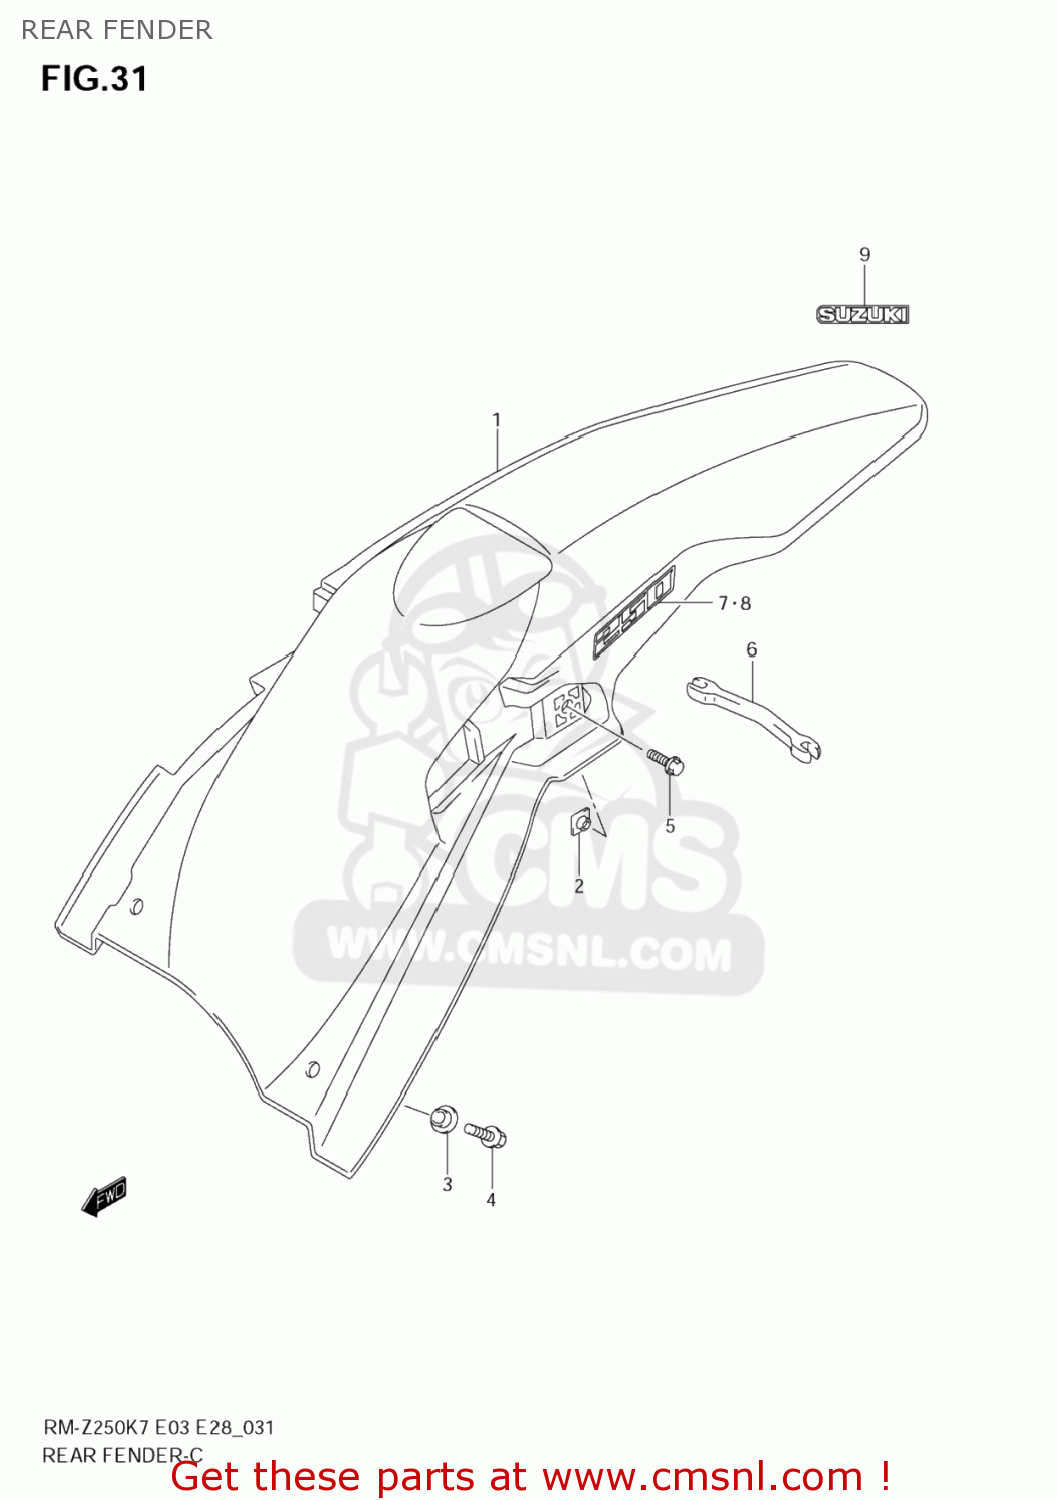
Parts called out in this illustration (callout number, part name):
1	FENDER,RR
2	NUT
3	WASHER
4	BOLT,6X20
5	BOLT(6X16)
6	OPEN SPANNER(6.4X6.8)
7	TAPE,RR FENDER,R
8	TAPE,RR FENDER,L
9	EMBLEM,RR
